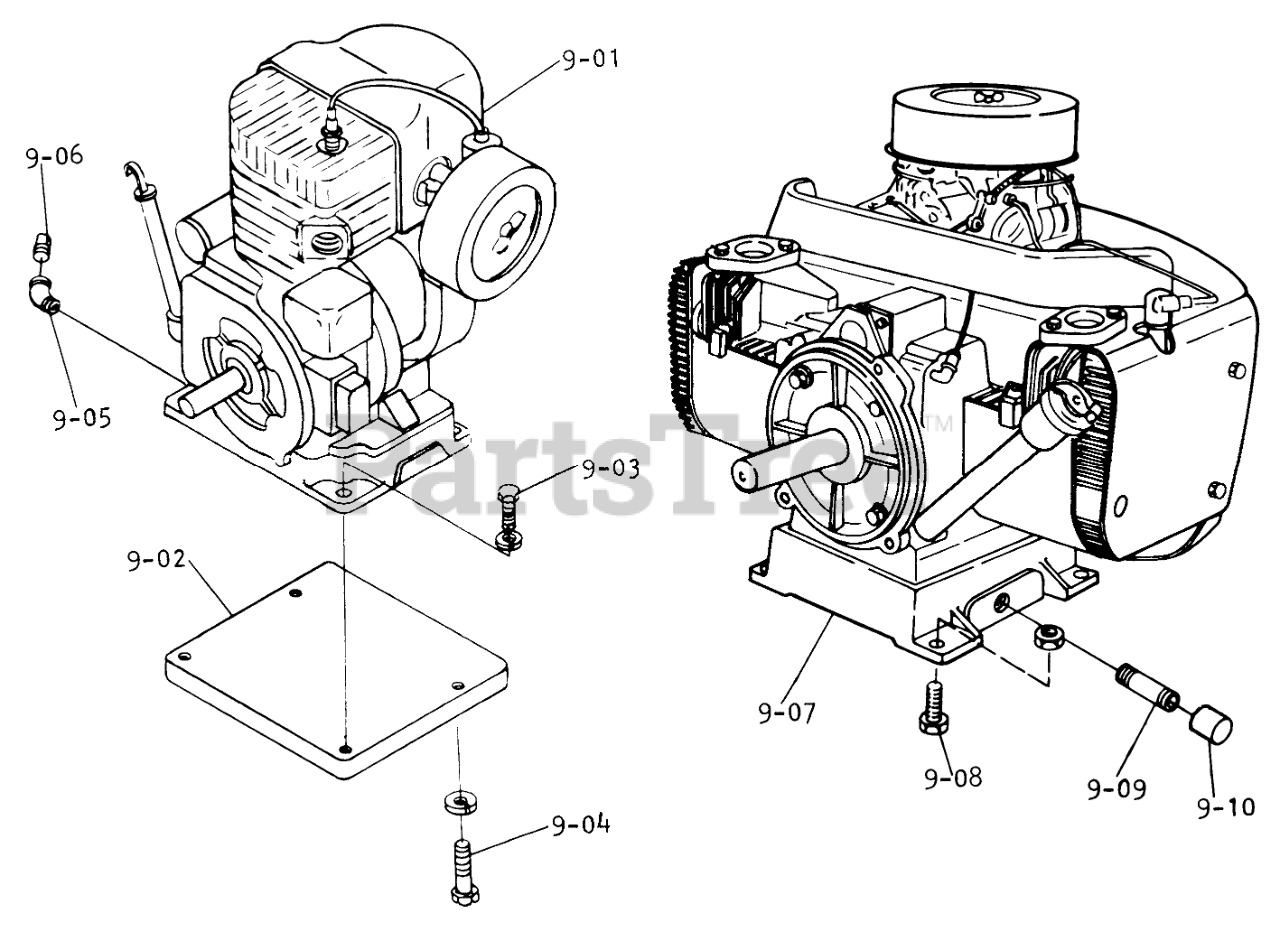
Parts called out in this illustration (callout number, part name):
9-01	Engine, 16 HP Kohler K341S-71141A
9-02	Engine Base, D-160
9-03	Bolt 3/8-16 x 1
9-04	Bolt Hex 1/2-13 x 1
9-05	Street Elbow, 3/8-45deg., (D-160)
9-06	Plug
9-07	Engine, 18 HP Kohler K482S-35222B
9-08	Bolt Hex 1/2-13 x 1 1/2
9-09	Nipple-Oil Drain 3/4 Pipe 2"
9-10	Cap-3/4 Pipe
